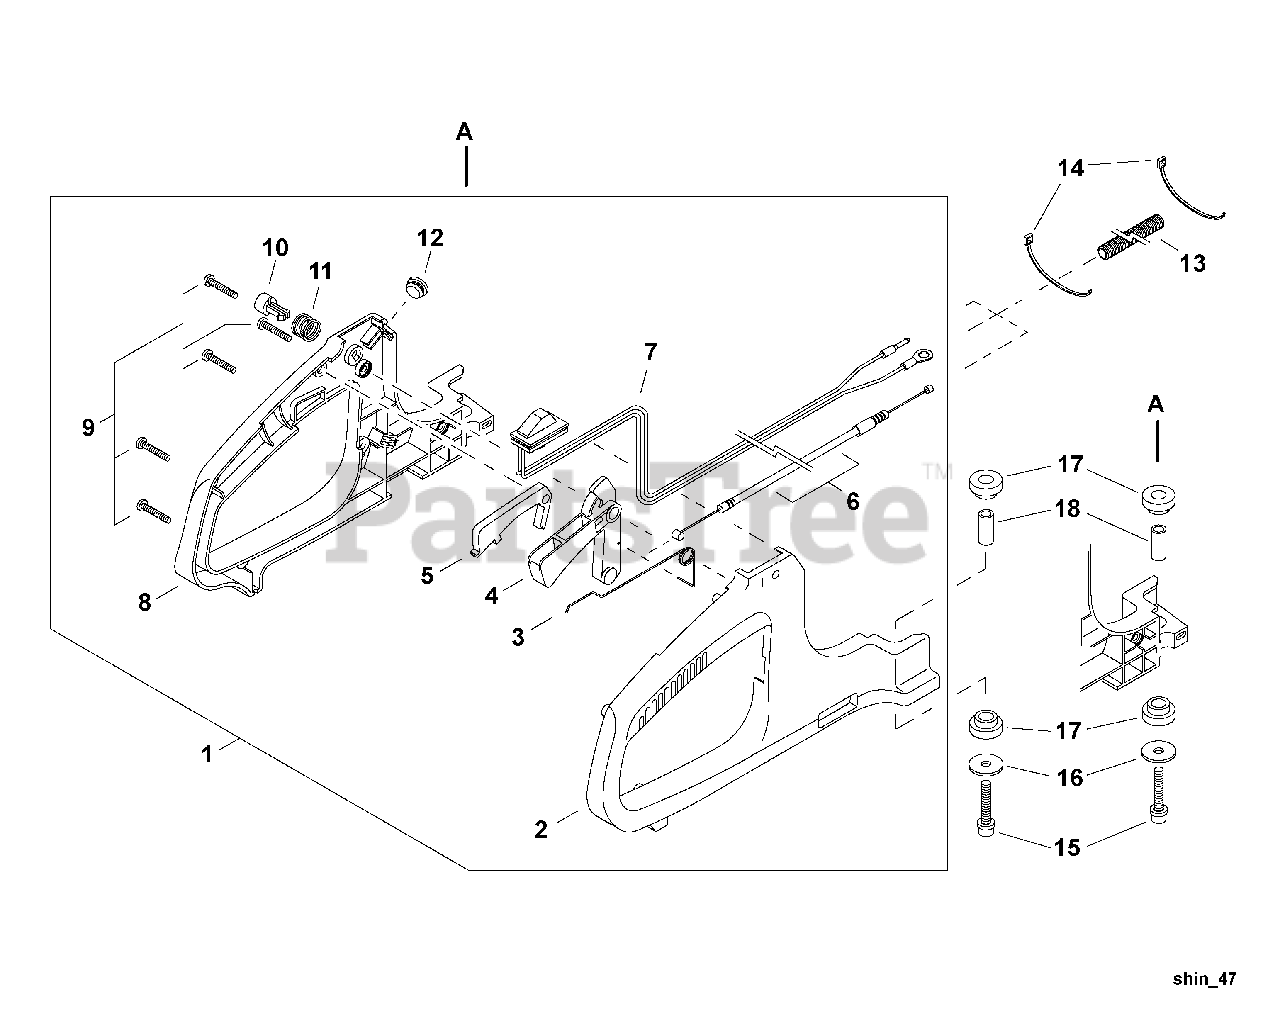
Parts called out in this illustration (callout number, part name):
1	HANDLE ASSY, REAR
2	CONTROL HANDLE - RIGHT
3	SPRING, THROTTLE RETURN
4	TRIGGER, THROTTLE
5	LEVER, THROTTLE LOCKOUT
6	CABLE, THROTTLE
7	SWITCH, ON-OFF
8	CONTROL HANDLE - LEFT
9	SCREW, TAPPING Ø4×18
10	BUTTON, THROTTLE LOCK
11	SPRING, COMPRESSION
12	PLUG, RUBBER
13	TUBE, FLEXIBLE L= 150
14	STRAP, TIE
15	BOLT M6×35
16	WASHER Ø23ר6.5×2 MM
17	CUSHION
18	COLLAR 6
